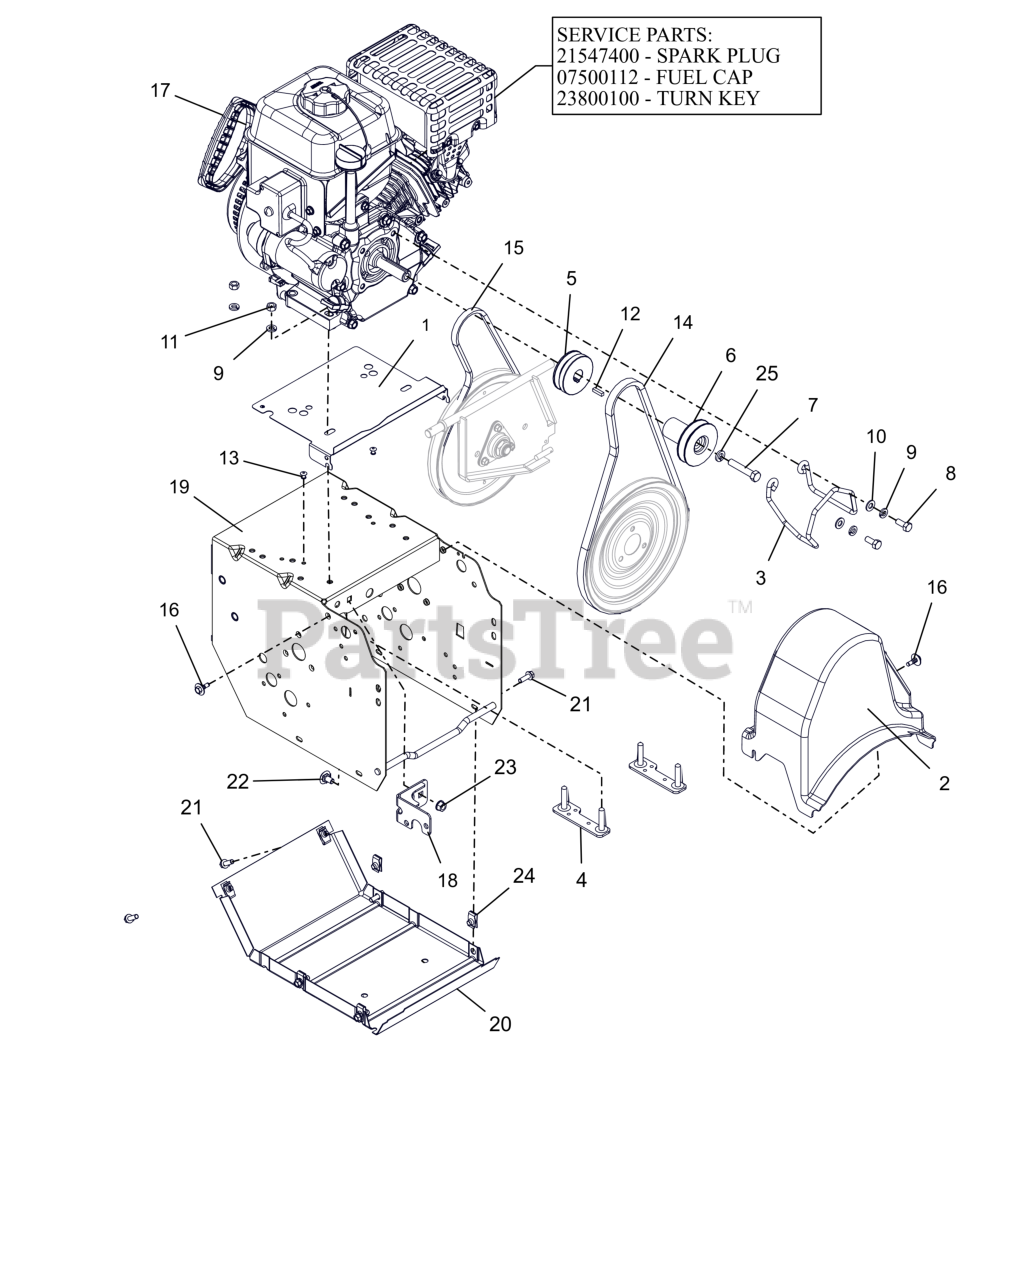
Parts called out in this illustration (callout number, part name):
1	BAFFLE, COMPACT
2	COVER, COMPACT BELT
3	FINGER, BELT
4	STRAP, ENGINE BOLT-WELDMENT
5	SHEAVE, TRACTION-COMPACT TRACK
6	SHEAVE,AUGER 3/4" PM
7	BLT, HEX .38-24X2.00 G5 ZCC
8	BLT, HEX .31-24X.750 G5 ZCC
9	WSHR, LK-HVY .312X.097 ZCC
10	WSHR,FLT .344X.688X.065 ZCC
11	NUT, HEX .312-18 ZCC
12	KEY-SQ .188X.75X.188
13	RVT, POP .1875 ZCC
14	V-BELT, HA-RAW EDGE
15	V-BELT, 3L-WRAPPED
16	SCR-TAP .25-20X.5 CAPTIVE
17	ENGINE, AX223 GEN 2 120V/60W
17	PLUG, SPARK
17	CAP, FUEL TANK BLACK
17	KEY, TURN LCT (2/PACKAGE)
18	WELDMENT, FRAME BRACKET
19	FRAME, MAIN-WELDMENT
20	COVER, BOTTOM
21	BLT, HWH .25-20X.75 G5 ZCC
22	BLT, RHSSN .31-18X.625 G5 ZCC
23	NUT-LK-TOP-FLG .312-18 GF ZCC
24	NUT-RTNR .25-20X.56
25	WSHR, LK-HVY .375X.115 ZCC
